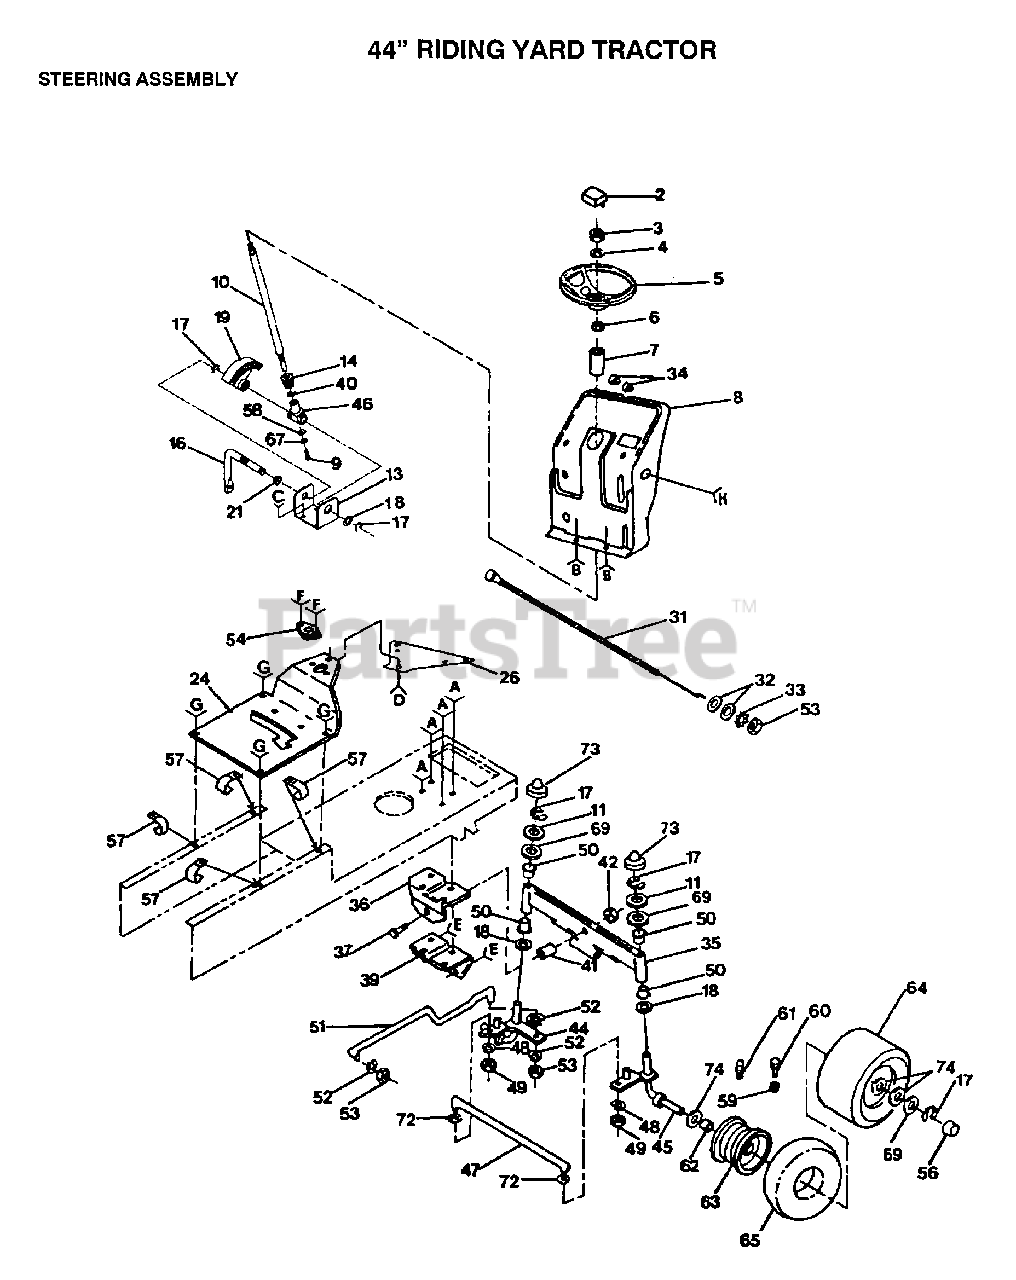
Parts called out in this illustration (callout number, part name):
2	INSERT-WHEEL LT
4	WASHER
6	ADAPTER LT
7	SLEEVE LTV
9	"SCREW,SPECIAL"
11	WASHER
13	"BRKT,STEERING"
14	"GEAR,PINION"
17	RING
18	WASHER .T
21	NYLINER T
32	WASHER
33	LOCKWASHER
34	PLUG-DASH T
35	FRONT AXLE
36	SUPPORT-SADDL T
37	BOLT LT
39	SUPPORT.SADDLE.FT
40	THRUST WASHER
41	BEARING
44	SPINDLE-LH LT
46	SUPPORT.SHAFT
47	ROD TIE
48	LOCKWASHER
49	NUT.LOCK.5/16-24
50	COL. SRTG. BEAR.
52	LOCKWASHER
56	HUB CAP
57	CLIP T
59	VALVE CAP
60	VALVE STEM LT
61	FITTING LT
62	"FLANGE, BEARING"
65	TUBE.5.3/4.5/6
67	LOCKWASHER
69	WASHER
72	WASHER M
73	CAP
74	WASHER
